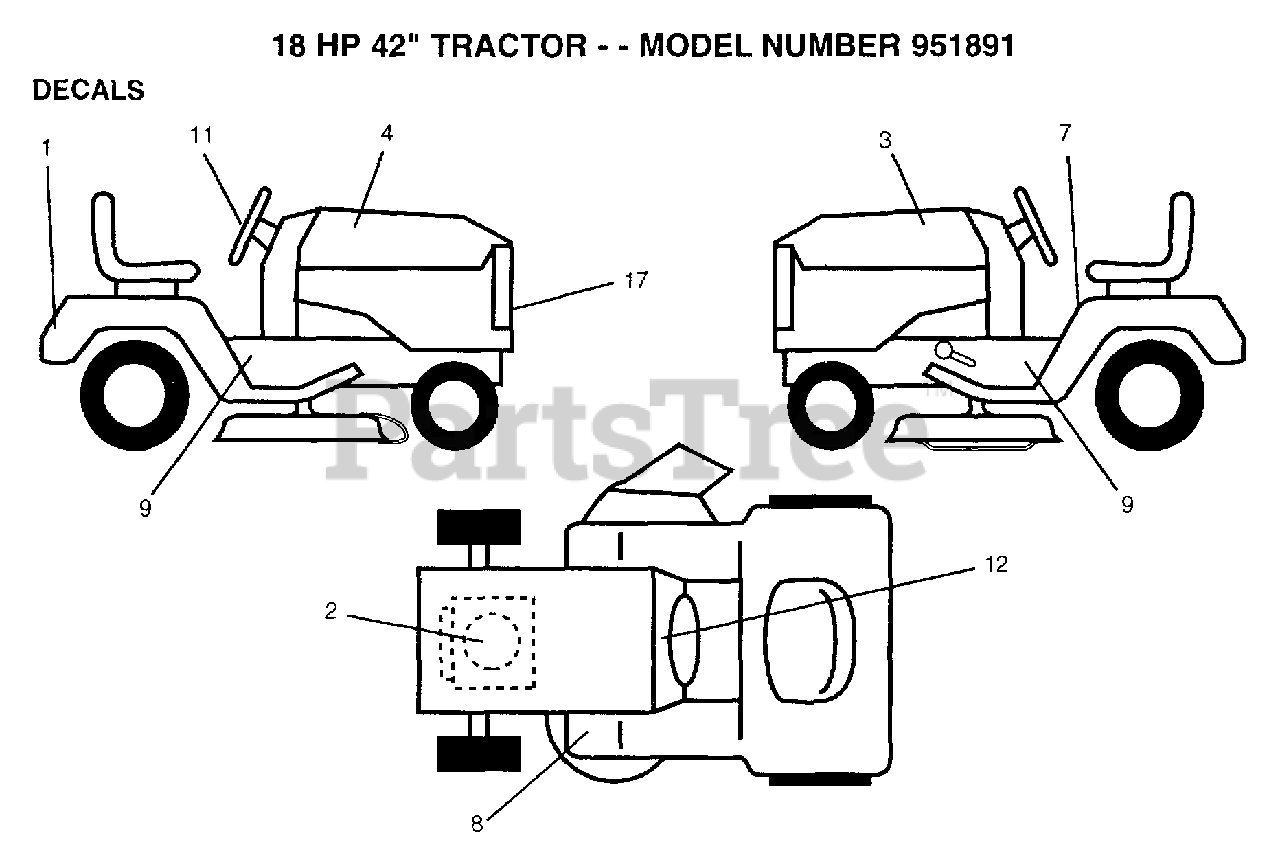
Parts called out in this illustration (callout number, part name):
1	DECAL.FENDER
2	DECAL.ENG.272757
4	DECAL.HOOD.RH
7	DECAL
9	DECAL.CHASSIS
11	DECAL.WHL.STRG
